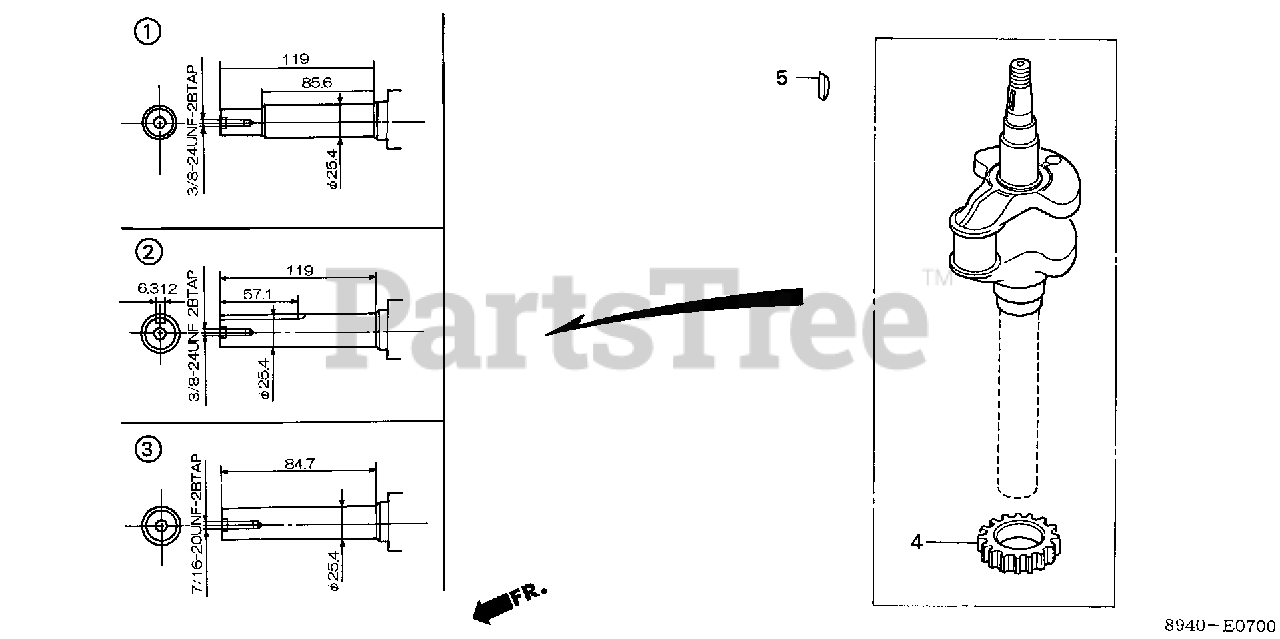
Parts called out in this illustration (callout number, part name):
1	CRANKSHAFT
4	GEAR, TIMING
5	KEY, SPECIAL WOODRUFF (25X18)
